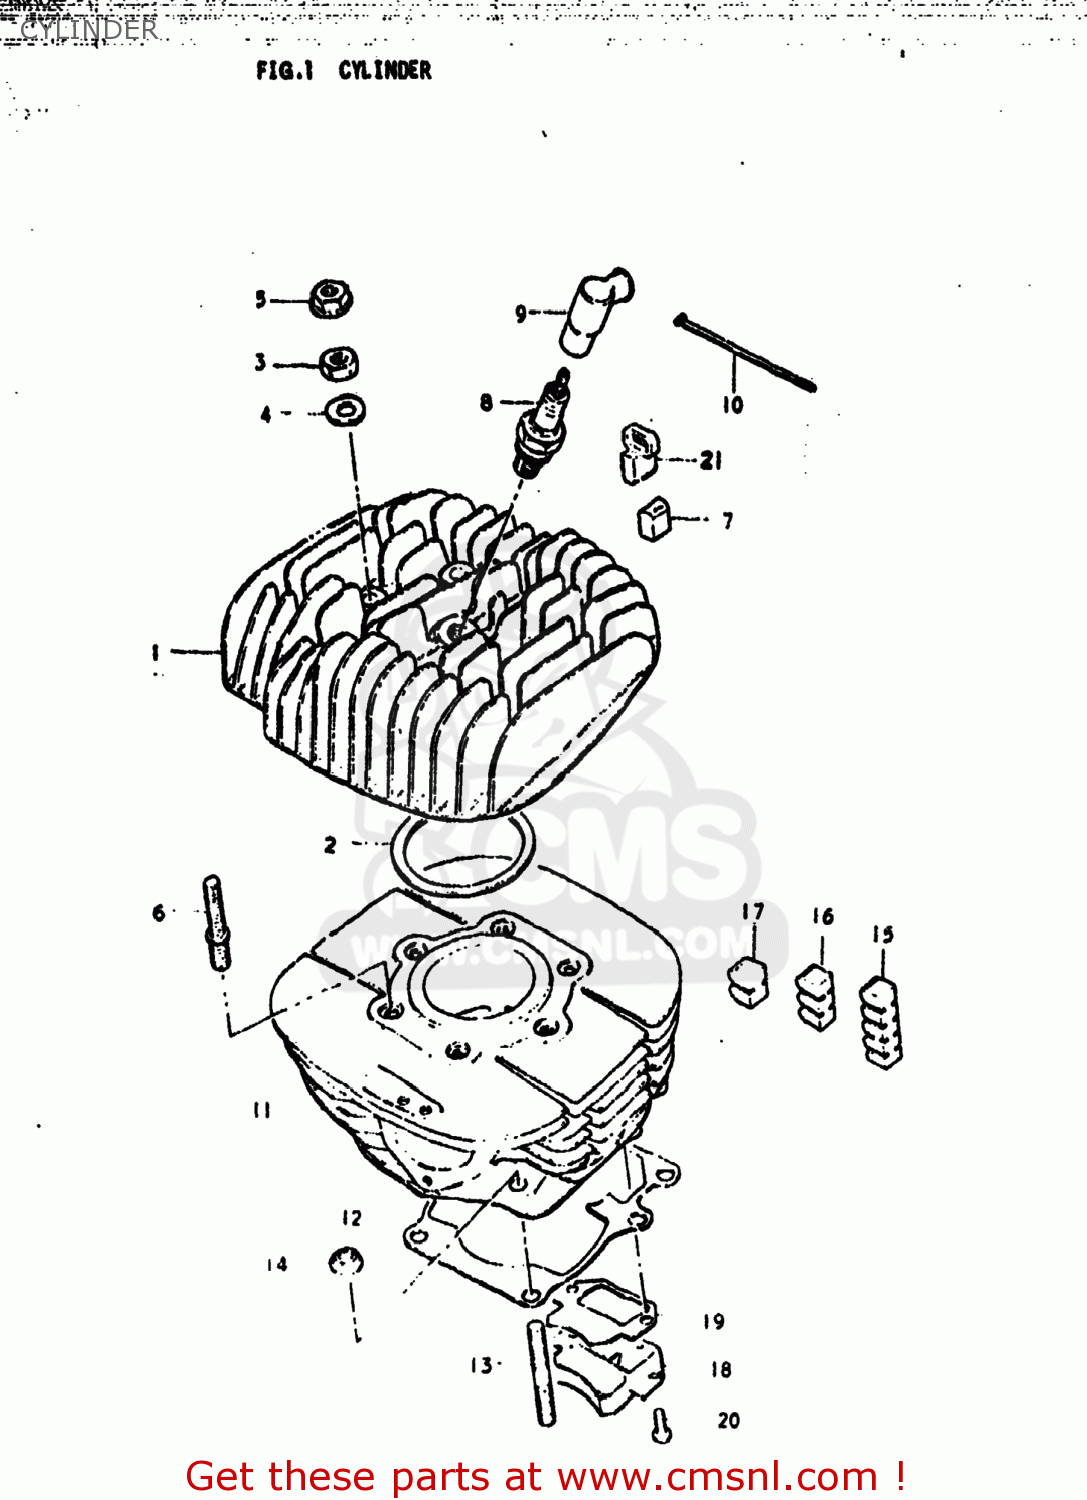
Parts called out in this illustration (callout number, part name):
1	HEAD,CYLINDER
2	GASKET,CYLINDER HEAD (NAS)
3	NUT (8MM)
4	WASHER
5	NUT
6	BOLT,STUD
7	PAD,CYLINDER
8	SPARK PLUG
9	CAP,SPARK PLUG
10	CLAMP
11	CYLINDER
12	GASKET,CYLINDER (MCA)
13	STUD 8X25
14	NUT
15	PAD,CYLINDER
16	PAD,CYLINDER
17	PAD,CYLINDER
18	VALVE ASSEMBLY,REED
19	GASKET,REED VALVE (MCA)
20	SCREW
21	GUIDE,CLUTCH CABLE
